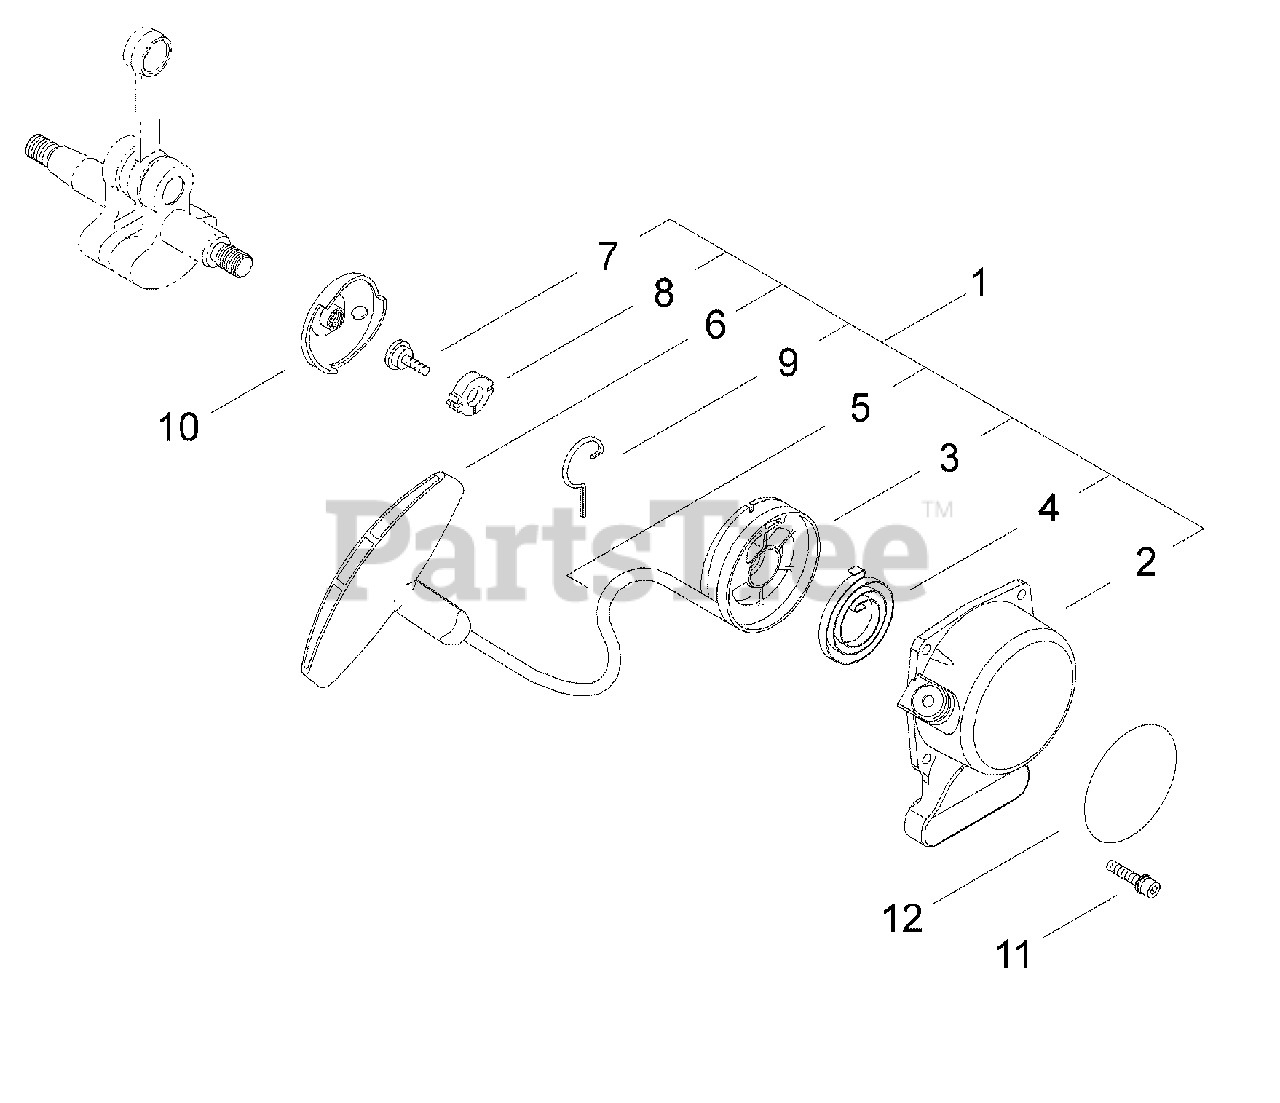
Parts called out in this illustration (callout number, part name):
1	STARTER ASSY, RECOIL
2	CASE, RECOIL STARTER
3	REEL, ROPE
4	SPRING, RECOIL
5	ROPE, STARTER
6	GRIP, STARTER
7	SCREW 5
8	WASHER 5
9	ARM, SWING
10	PULLEY, STARTER
11	BOLT M4×14
12	LABEL, RECOIL C4
